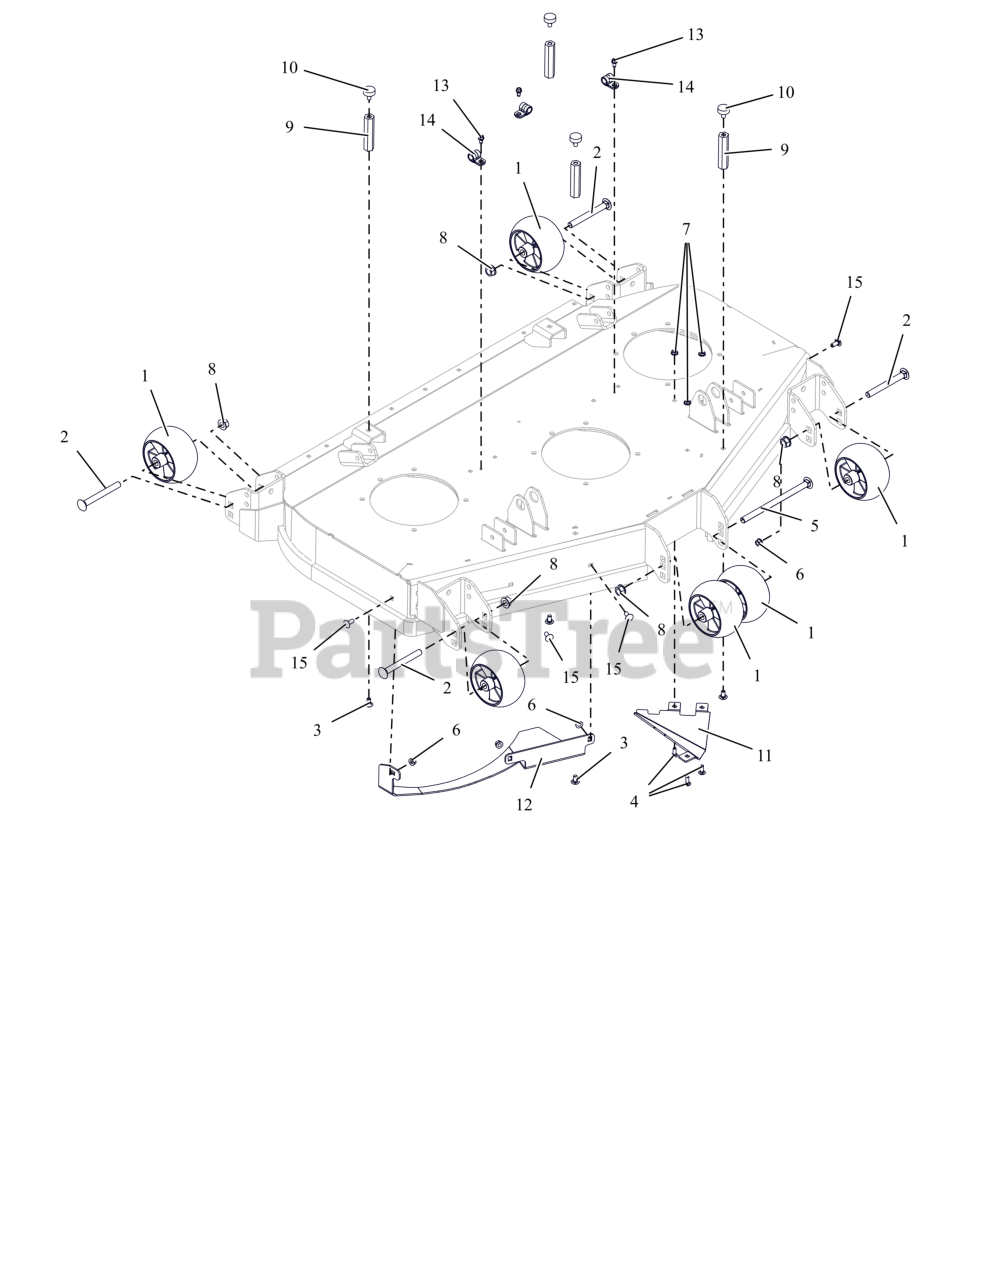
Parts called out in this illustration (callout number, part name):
1	WHEEL, ANTI SCALP - 5X3 CTR W/RIBS
2	BLT-RHNS .50-13X4.50 G5 ZCC NS
3	BLT,RHSSN.31-18X.625 G5 ZCCP30
4	BLT, RHSN .25-20X.750 G5 ZCC
5	BLT-RHSN .50-13X8.00 G5 ZCC NS
6	NUT,LK-CTR-FLG .31-18 GF ZCC
7	NUT-LK-CTR-FLG .25-20 ZC120
8	NUT-LK-CTR-FLG .500-13 GG ZCC
9	NUT, COUPLING .312-18 X 3.375
10	BUMPER, RUBBER
11	BAFFLE, 48" TRIANGLULAR INSERT (ORANGE)
12	DEFLECTOR, BAFFLE BOLT-IN (ORANGE)
13	SCR-TAP .25-20X.50 HWH ZCC
14	CLAMP, CUSHIONED STEEL
15	BLT, RHSSN.31-18X.750 G5 ZCC
